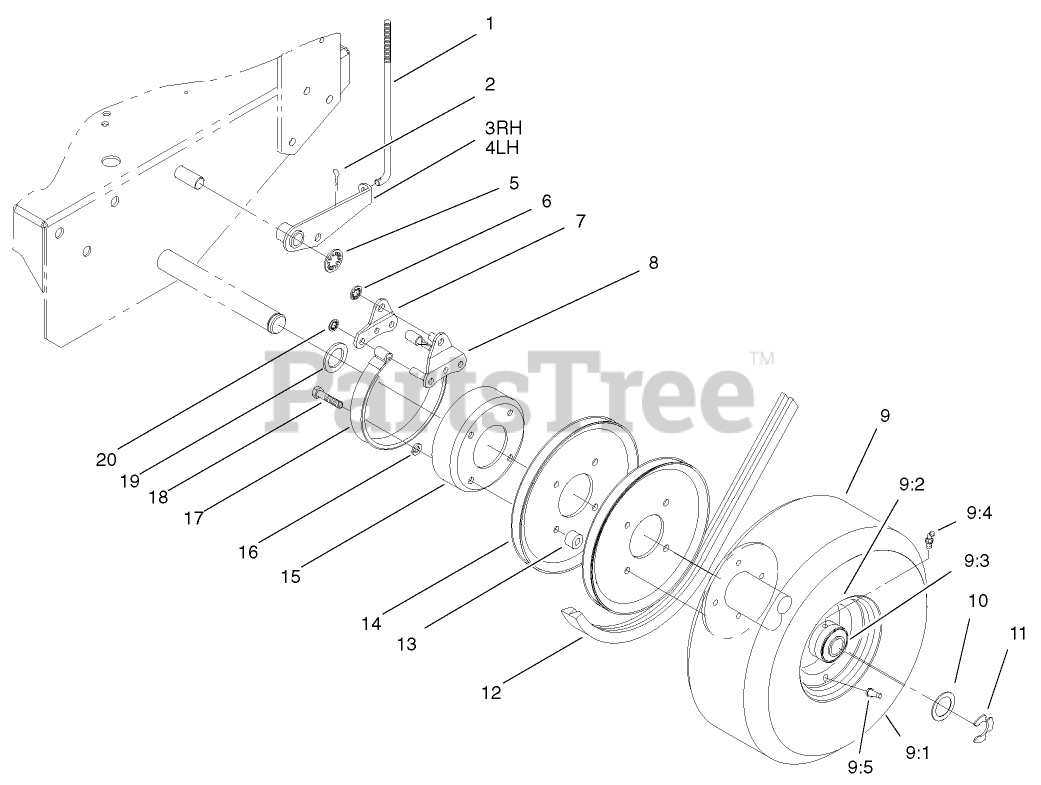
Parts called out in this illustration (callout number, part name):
1	ROD-BRAKE
2	PIN-COTTER
3	ARM-BRAKE, RH
4	ARM-BRAKE, LH
5	RING-RETAINING
6	RING-RETAINING, EXTERNAL
7	PLATE-LINK, BRAKE
8	LINK-BRAKE
9	WHEEL AND TIRE ASM
9:1	TIRE-FRONT
9:2	WHEEL ASM
9:3	BEARING-BALL
9:4	FITTING-GREASE
9:5	STEM-VALVE
10	WASHER-THRUST
11	RING-RETAINING
12	V-BELT
13	SPACER-PULLEY
14	PULLEY-WHEEL
15	DRUM-BRAKE
16	WASHER-LOCK
17	BAND-BRAKE
18	SCREW-HH
19	WASHER-WHEEL
20	RING-RETAINING
